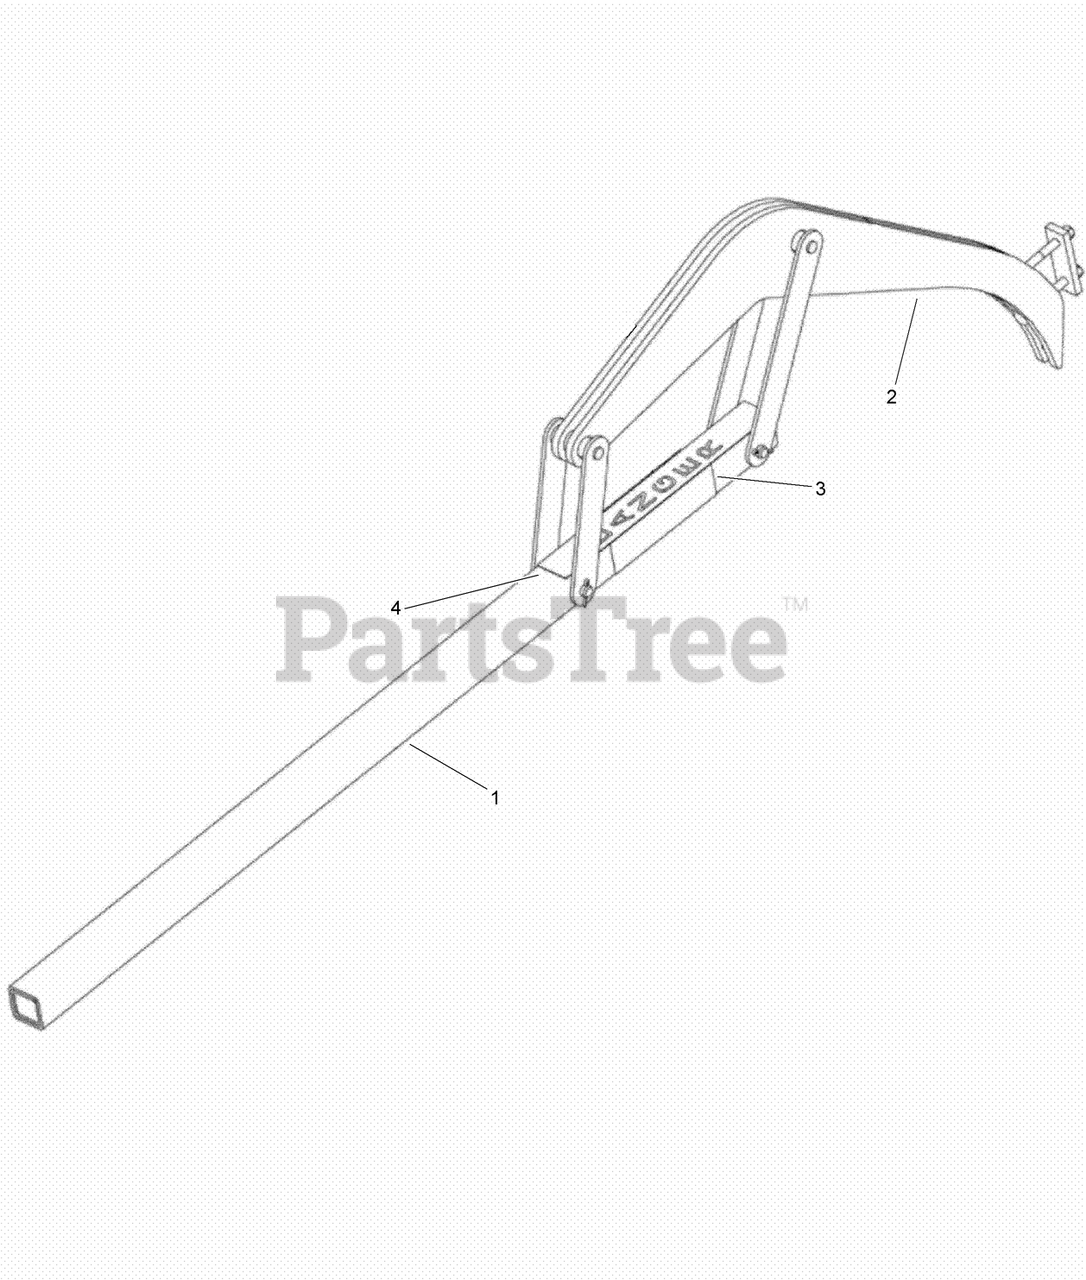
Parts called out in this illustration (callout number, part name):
1	BOOM-crumber, 6 foot, heavy duty planetary trencher
2	I / BASIC CRUMBER ASM
3	DECAL-Danger, Entanglement Hazard
4	DECAL-Danger
